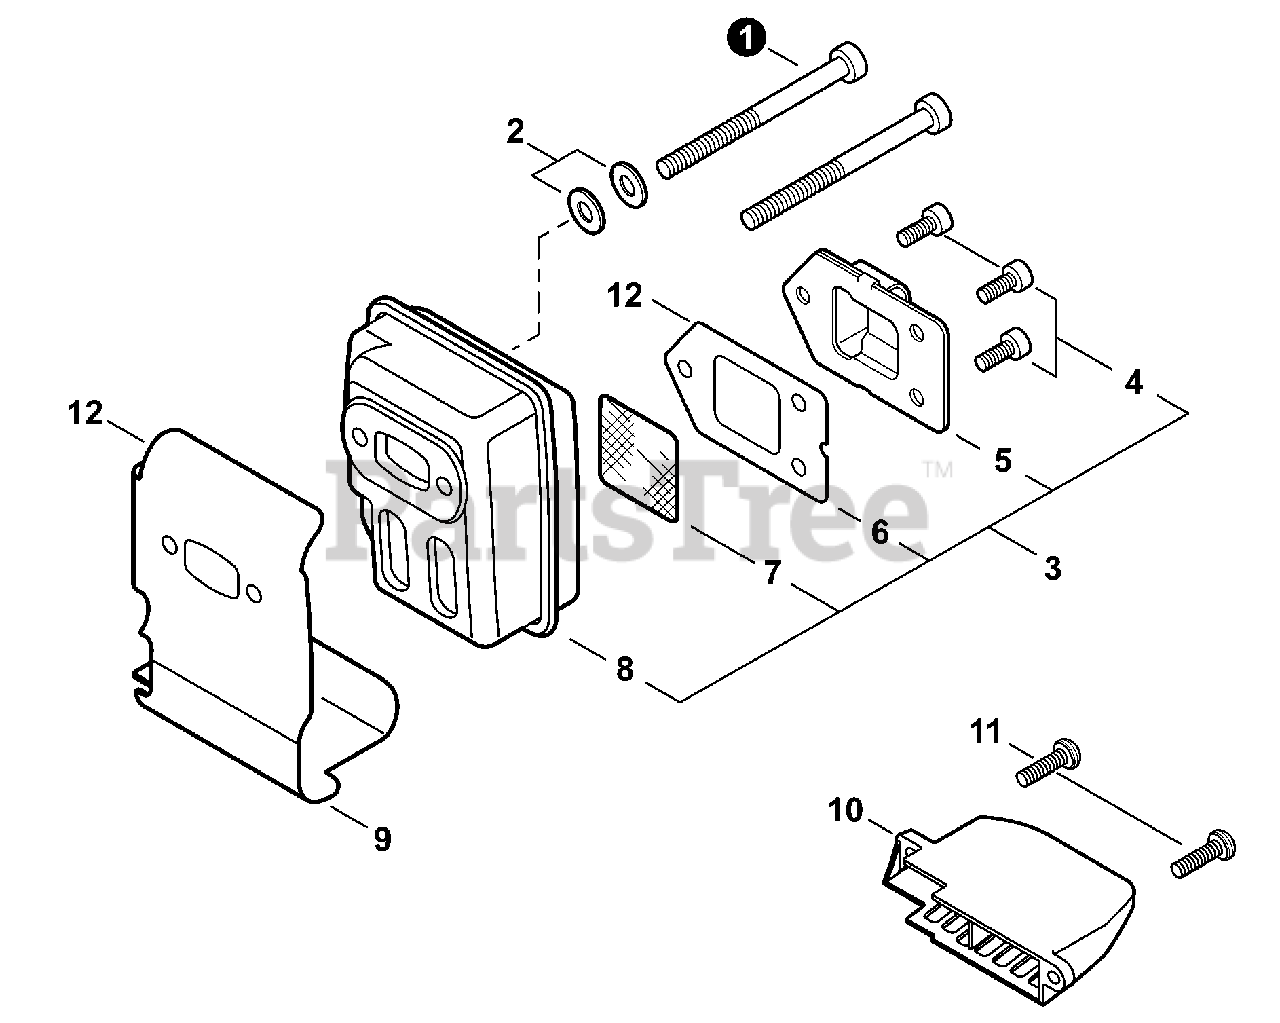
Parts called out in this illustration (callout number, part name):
1	SCREW - 5×55
2	WASHER - CONICAL
3	MUFFLER ASSY
4	SCREW - 4×8 -- TORX
5	GUIDE, EXHAUST
6	GASKET, EXHAUST
7	SCREEN, SPARK ARRESTER
9	SHIELD, EXHAUST
10	DUCT, AIR
11	SCREW - 5×16
12	GASKET KIT
